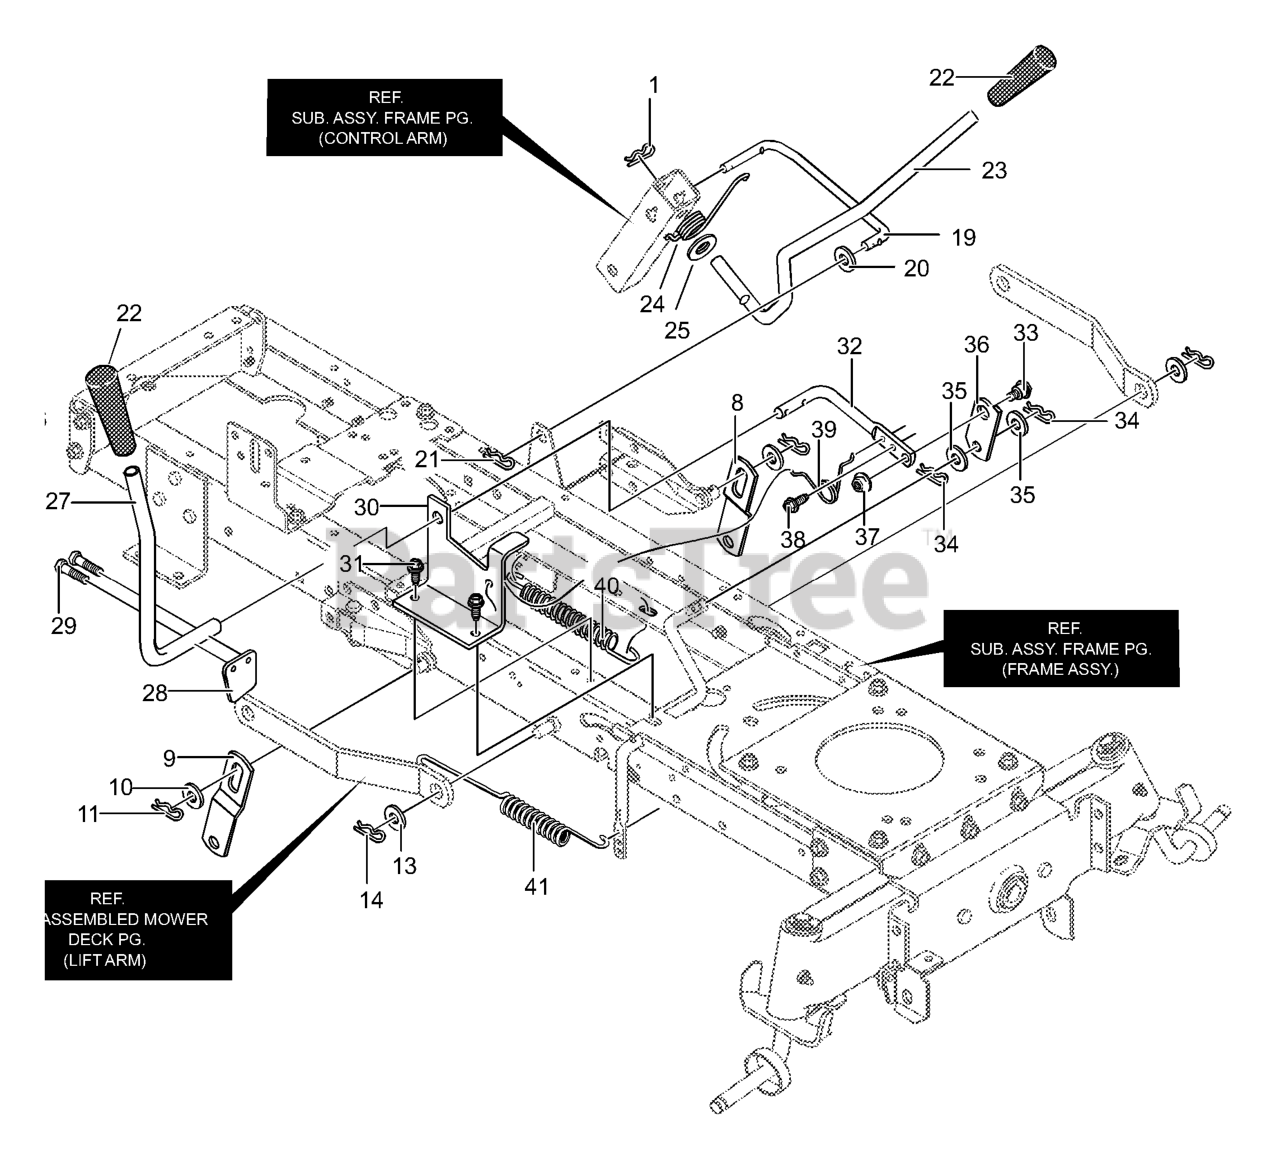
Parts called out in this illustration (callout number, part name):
1	PIN, HAIR
8	LINK, LIFT LH
9	LINK, LIFT RH
10	WASHER, FLAT
11	PIN, HAIR
13	WASHER, FLAT
14	PIN, HAIR
19	LINK LIFT HANDLE
20	WASHER, FLAT
21	PIN, HAIR
22	GRIP, DLX GREY
23	HANDLE, LIFT
24	WASHER, FLAT
25	TORSION SPRING
26	GRIP, PTO DLX GREY
27	PTO HANDLE H26
28	PADDLE, SWITCH
30	BRACKET, PTO
31	SCREW, 5/16-18 x 0.50
32	LEVER, PTO
34	PIN, HAIR
35	WASH, FLAT
36	LINK PTO
37	NUT, 3/8-16
38	SCREW 5/16-18X.75
39	TORISON SPRING
40	SPRING, EXTENSION
41	SPRING, EXTENSION
